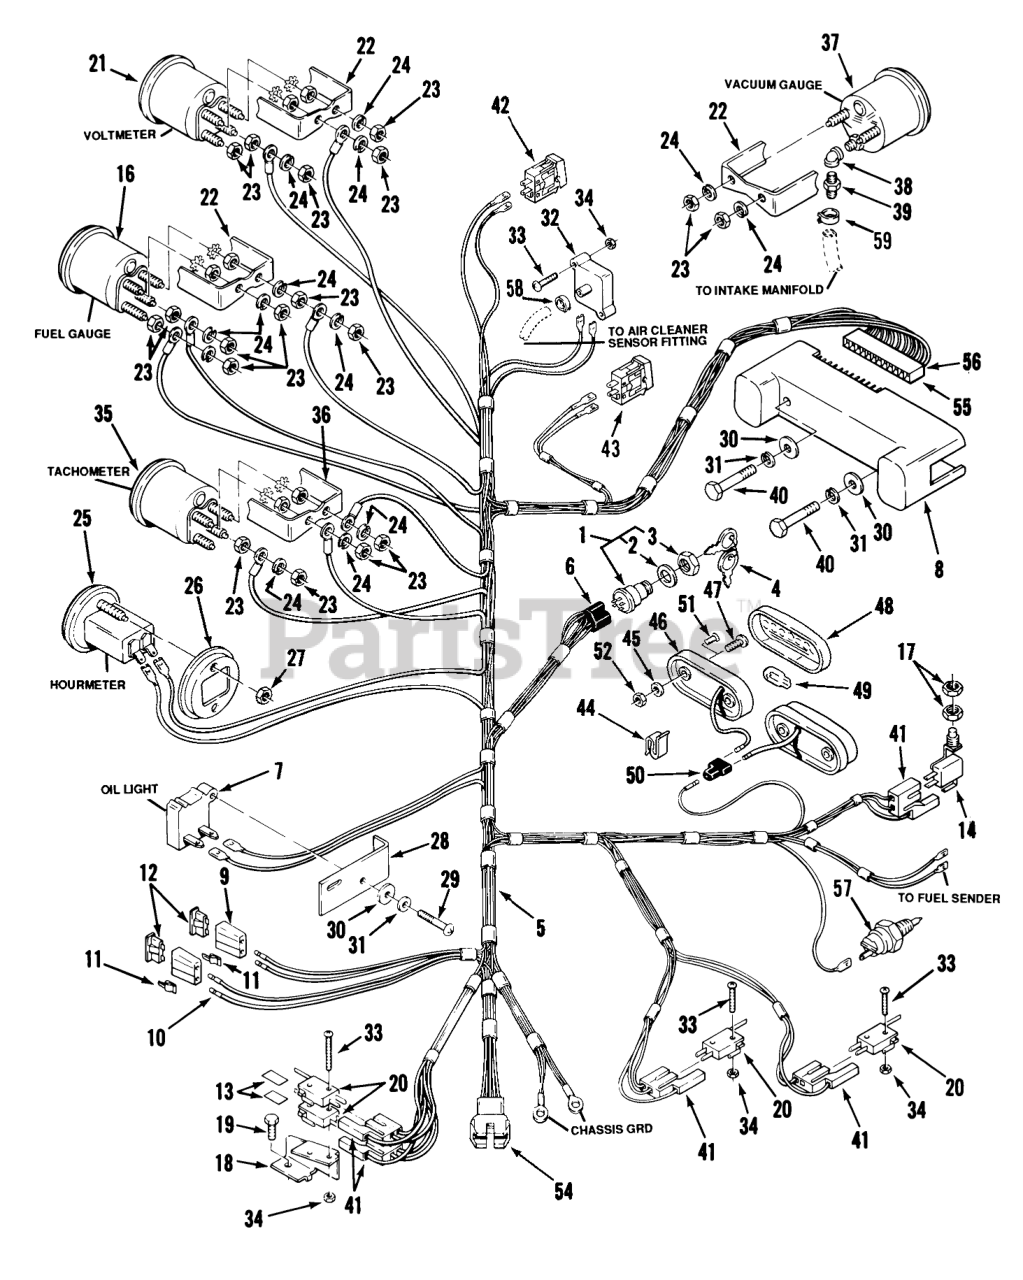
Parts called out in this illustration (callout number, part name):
1	IGNITION SWITCH ASM
2	LOCKWASHER
3	NUT BEZEL
4	Ignition Key
4	KEY PADDED
5	HARNESS-WIRE
5	WIRING-HARNESS
6	CONNECTOR-5 WAY-SERV
7	LIGHT-OIL PRES (5)
8	8-Light Circuit Module 520-H Only
8	CIRCUIT-BRD 6 LITE
9	AUTO-FUSEBLOCK TERM
10	TERMINAL FUSE
12	FUSE-10 AMP
12	FUSE-BLADE, 20 AMP
13	BARRIER - SWITCH
14	Seat Switch
16	Fuel Gauge (includes item 22) All models
17	NUT-HEX, SPECIAL
18	Support-Switch
18	RECEPTACLE TERMINAL
19	Bolt
20	SWITCH
21	Voltmeter (includes item 22) All models
22	BRKT-GAUGE MOUNTING
23	Nut
24	Lockwasher
25	Hourmeter (includes item 26) 518 & 520-s
26	BRKT-GAUGE MOUNTING
27	Hex Nut
28	Light Bracket 516
29	SCREW-PHCR #8-32X.75
30	WASHER
31	LOCKWASHER
32	SENSOR-AIR CLEANER
33	Screw
34	NUT HEX 4-40 ELAST
35	Tachometer (includes item 36) 520-s
36	MOUNTING-BRACKET
37	Vacuum Gauge (includes item 22) 520-s
38	ELBOW
39	FITTING STRAIGHT
40	SCREW
41	CONNECTOR BODY
42	Light Switch
43	SWITCH-TEST
44	SPEED CLIP
45	Lockwasher
46	BASE-TAIL LIGHT
47	Screw
48	LENS-TAIL LIGHT
49	LIGHT BULB
50	CONNECTOR 3 WIRE
51	RIVET-4
52	Nut
53	WASHER
54	9-CIRCUIT CAP
55	Connector-Male
56	Terminal
57	SENSOR-HYDRO OIL HOT
58	CLAMP-HOSE 5/16"
59	Clamp
